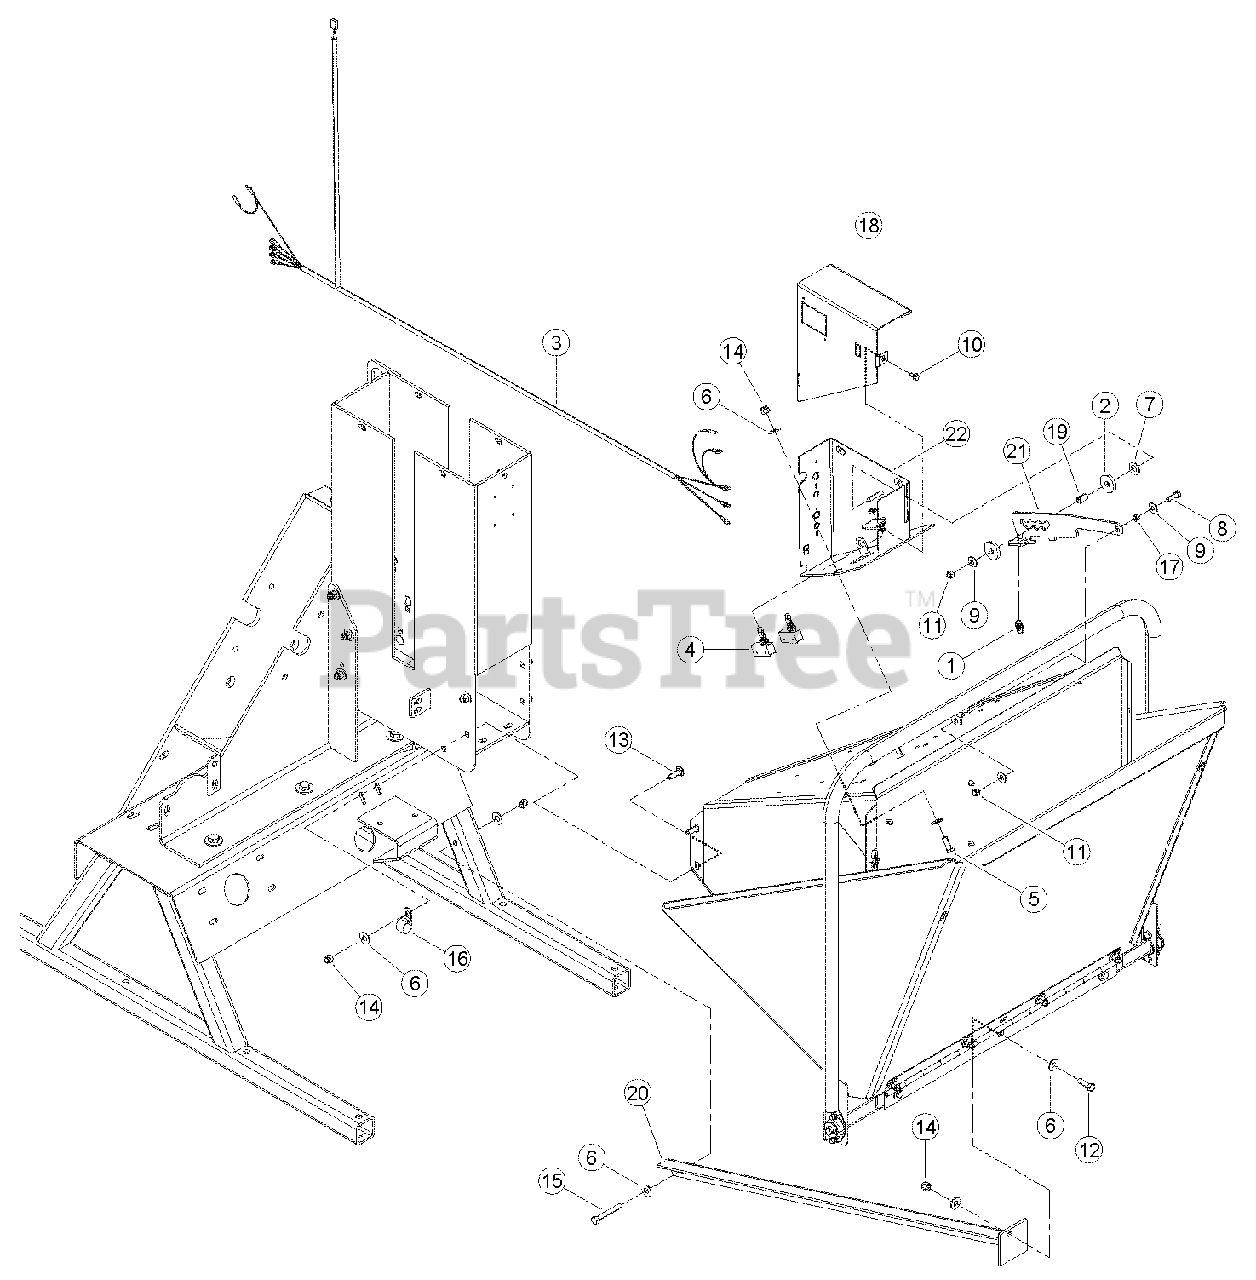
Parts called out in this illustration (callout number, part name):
1	BOLT, 1/4 X 1 HEX GR5 ZP
2	BOLT, 3/8 X 1 HEX GR5 ZP
3	WASHER, 1/4 FLAT ZP
4	WASHER, 3/8 FLAT ZP
5	BOLT, 1/4 X 2-1/4 HEX GR5 ZP
6	BOLT, 1/4 X 1-1/4 HEX GR5 ZP
7	BOLT, 5/16 X 1 HEX GR5 NC ZP
8	WASHER, 5/16 FLAT ZP
9	BOLT, 1/4 X 5/8 HEX GR5 ZP
10	NUT, 1/4 NE NYLOCK ZP
11	NUT, 5/16 NE NYLOCK ZP
12	BOLT, 3/8 X 1-1/4 HEX GR5 ZP
13	BOLT, 3/8 X 1-1/4 CRG GR5 ZP
14	NUT, 3/8 NE NYLOCK ZP
15	BOLT, 3/8 X 2-3/4 HEX GR5 ZP
16	RIVET, AL BLIND 1/4 X 3/4 DOME HEAD
17	CLAMP, 1" COATED METAL
18	CLAMP, CABLE MOUNT
19	CIRCUIT BREAKER, 10 AMP RESETTABLE
20	HARNESS, 5 IN PTO PLUS 1 CONTROLLER
21	CONTROLLER, PLUS 1 CHIPPER
22	BUMPER, 1" OD W/1/4" STUD
23	SPACER, IDLER PIVOT
24	WELDMENT, CHUTE SUPPORT
25	ENCLOSURE, PLUS 1 MOUNT
26	ASSEMBLY, SWITCH BOX
